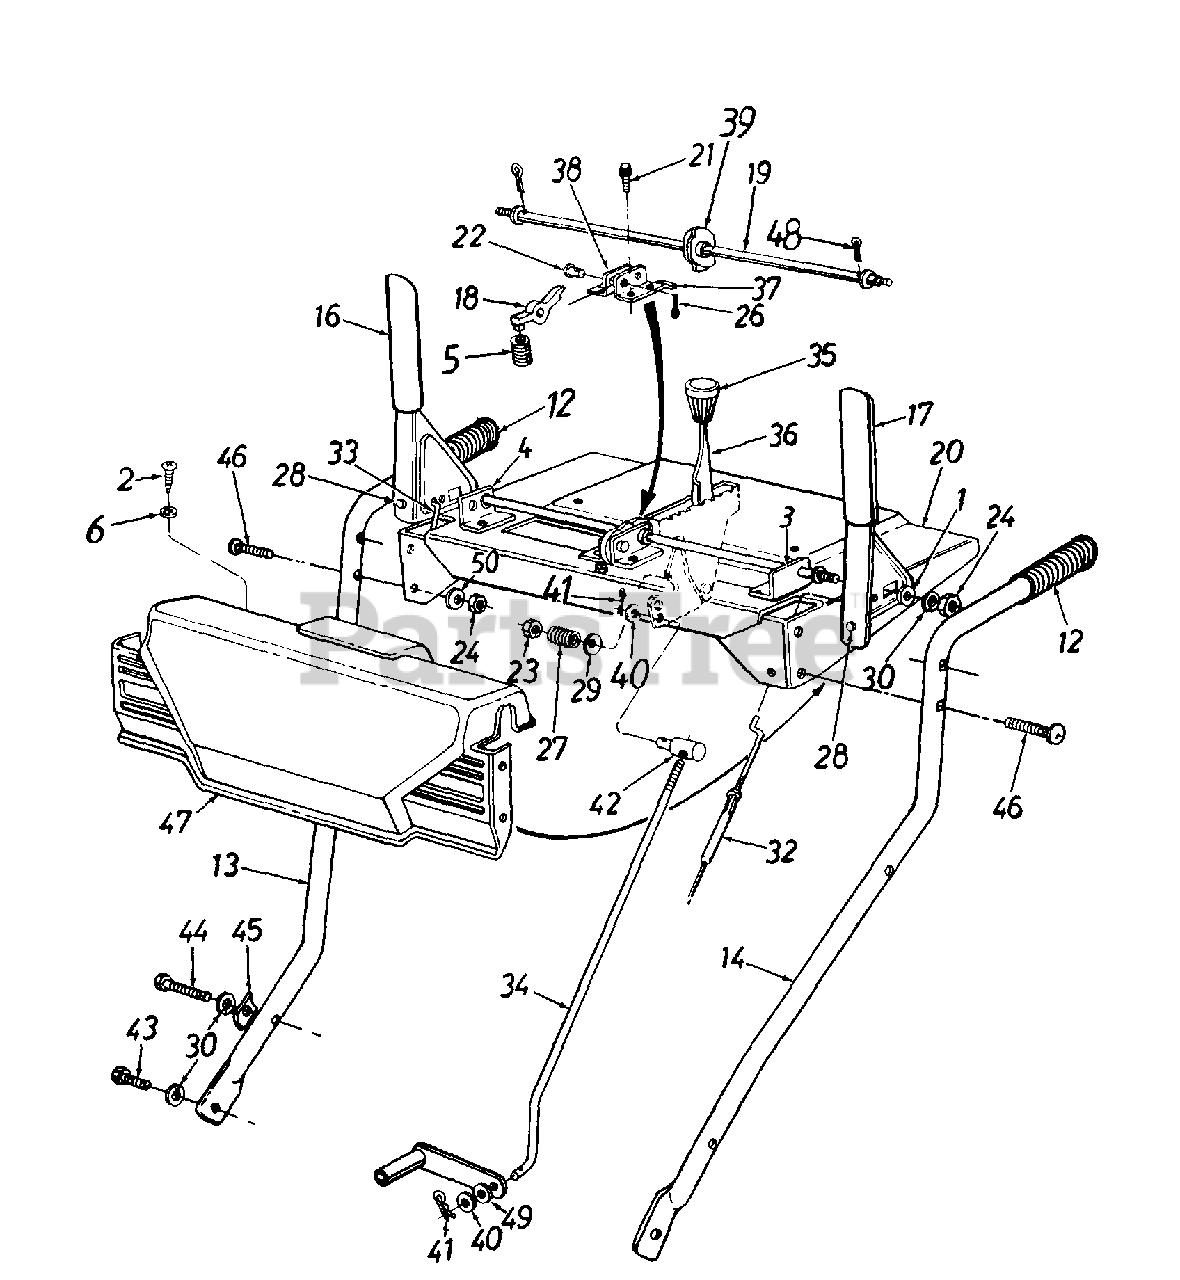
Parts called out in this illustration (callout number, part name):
2	Truss Mach. B-Tap Scr. #10 x .5
5	Compression Spring
6	Fl-Wash .188" I.D. x .43" O.D.
13	Handle - R.H.
14	Handle - L.H.
16	Engagement Handle - R.H.
17	Engagement Handle - L.H.
18	Pawl Handle Lock
19	Rod Cam
22	Clevis Pin .437" Dia. x .65" Lg.
23	Hex Ins. L-Nut 3/8-24 Thd.
24	Hex Nut 5/16-18 Thd.
26	Cotter Pin 3/32" Dia. x 1" Lg.
27	Compression Spring
28	Rubber Bumper
29	Bell-Wash .38" I.D. x .88" O.D.
30	L-Wash 5/16" I.D.
32	Auger Clutch Cable
33	Drive Clutch Cable
34	Shift Rod
35	Shift Knob
36	Shift Handle
39	Cam Handle Lock
40	Fl-Wash .344" I.D. x 62" O.D.
41	Internal Cotter Pin 5/16" Dia
42	Ferrule
43	Hex Bolt 5/16-18 x .62" Lg.
44	Hex Bolt 5/16-18 x 1.75" Lg. (Gr. 5)
45	Handle Tab
46	Curved Carr Bolt 5/16-18 x 1.5"
47	Handle Panel
48	Cotter Pin 3/32" Dia. x .75" Lg.
49	Spr. Wash .32" I D. x 62" O.D.
50	Bell-Wash .325" I D. x .88" O.D.
